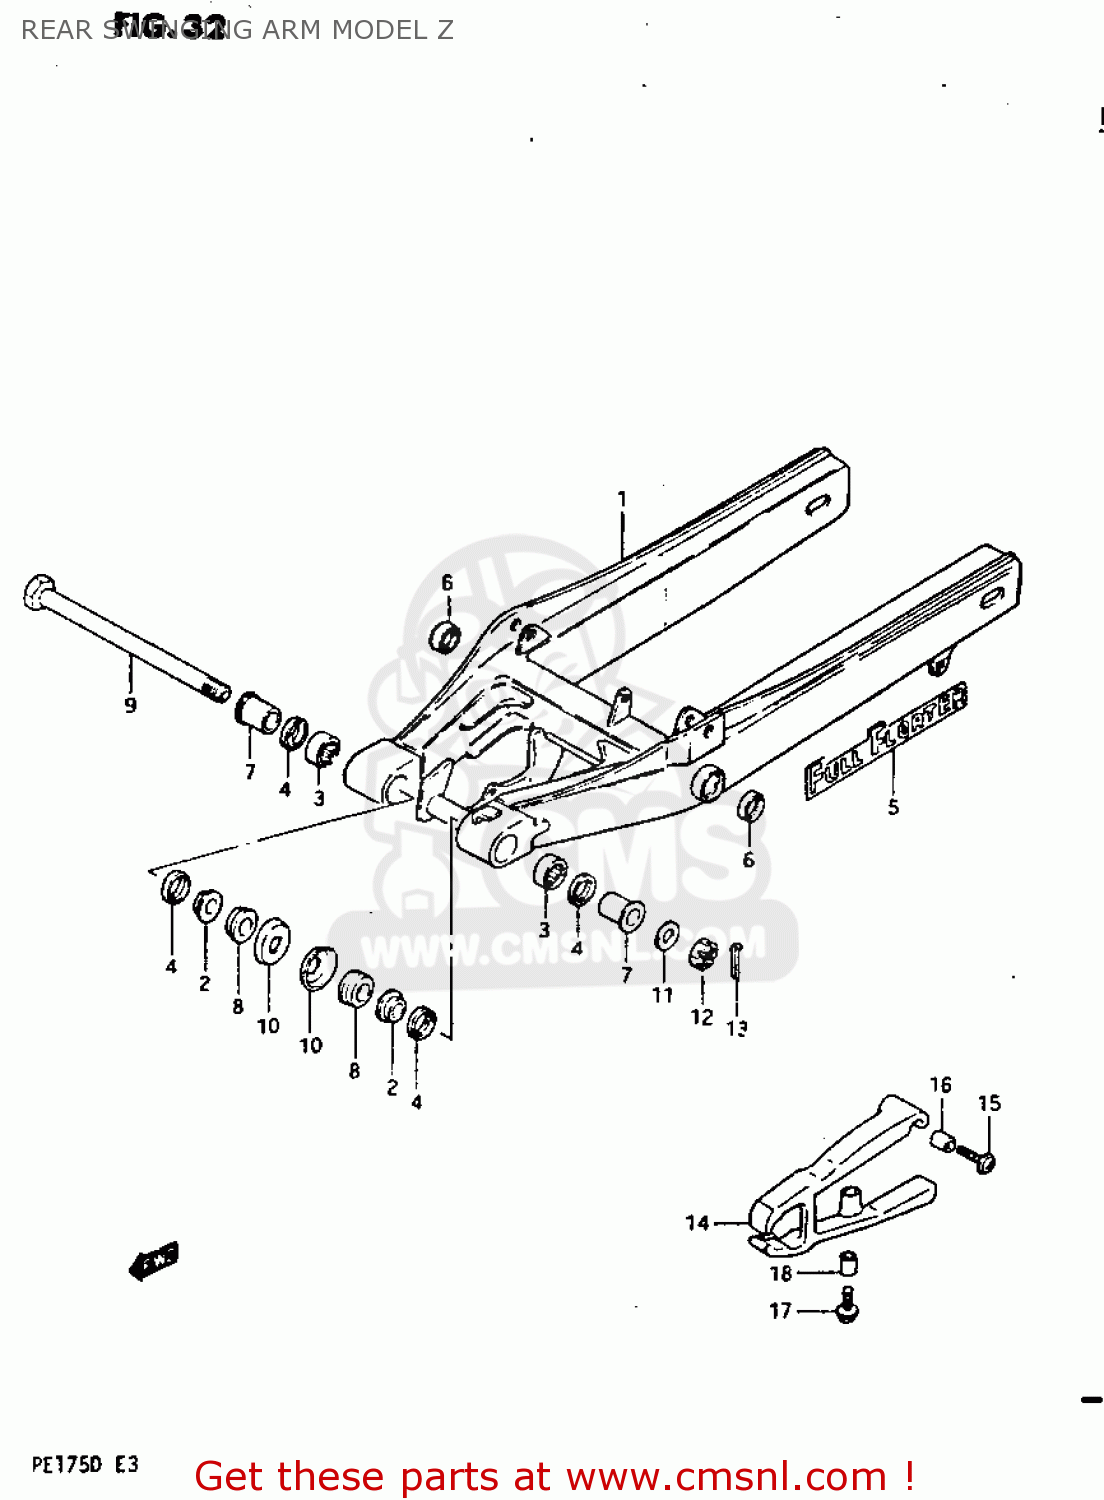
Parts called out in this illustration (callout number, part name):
1	SWING ARM ASSEMBLY,REAR
2	BUSH,RR SWINGINGARM PIVOT
3	BEARING(20X27X20)
4	OIL SEAL
5	EMBLEM,SWING ARM
6	OIL SEAL
7	SPACER,RR SWGARM PIVOT
8	SPACER,RR SWGARM PIVOT INNER
9	SHAFT,RR SWINGINGARM PIVOT
10	COVER,RR SWGARM DUST SEAL
11	WASHER
12	NUT 14MM
13	COTTER PIN
14	BUFFER,CHAIN TOUCH DEFENSE
15	BOLT,CHAIN TOUCH DEFEND
16	SPACER (6.1X9X9)
17	BOLT,CHAIN TOUCH DEFEND
18	SPACER(6.5X10.5X22.5)
